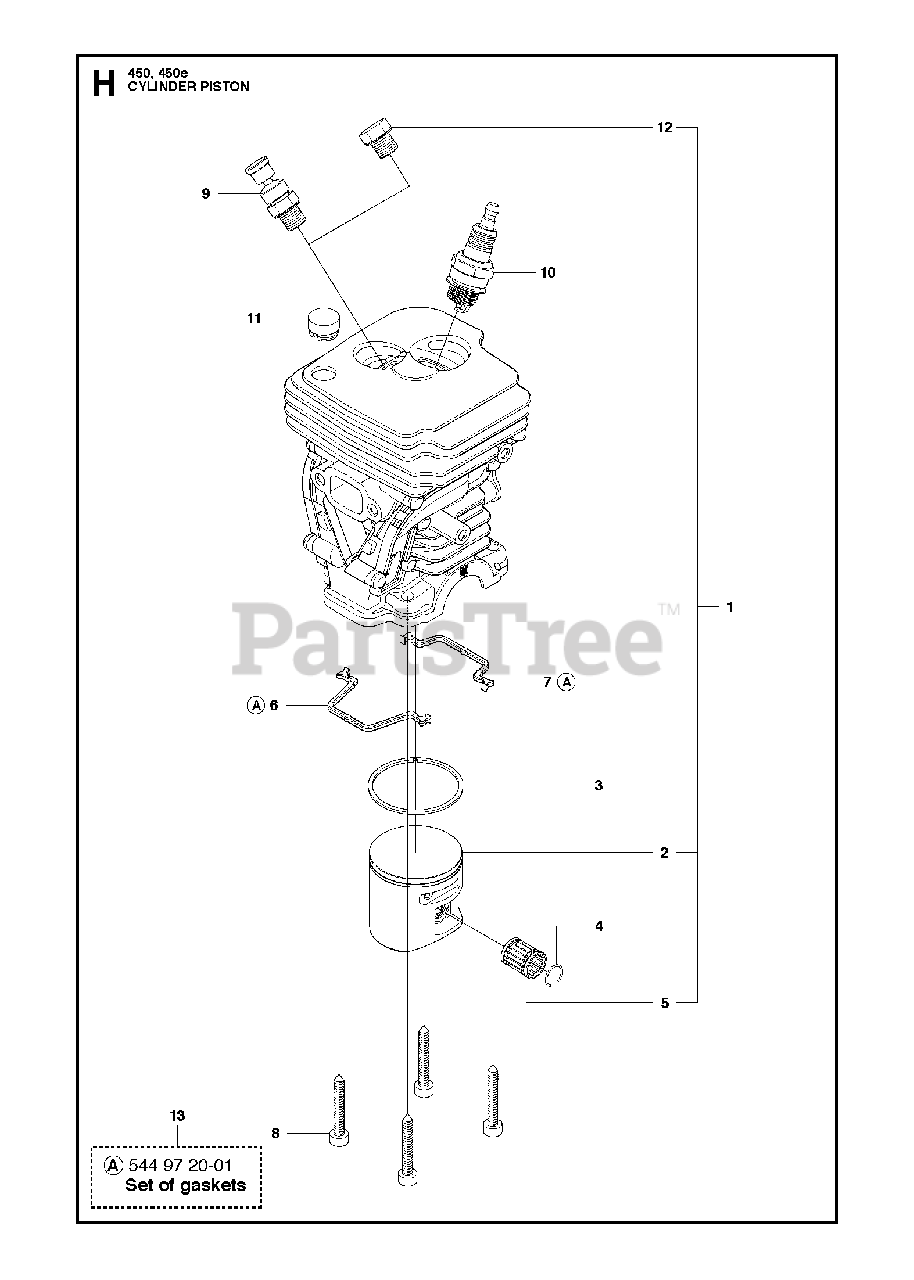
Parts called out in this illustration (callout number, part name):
2	PISTON ASSY
3	PISTON RING
4	CIRCLIP
5	NEEDLE BEARING
6	GASKET
7	GASKET
9	DECOMPRESSION VALVE
10	BPMR7A NGK SPARK PLUG
12	CYLINDER PLUG
13	GASKET KIT
